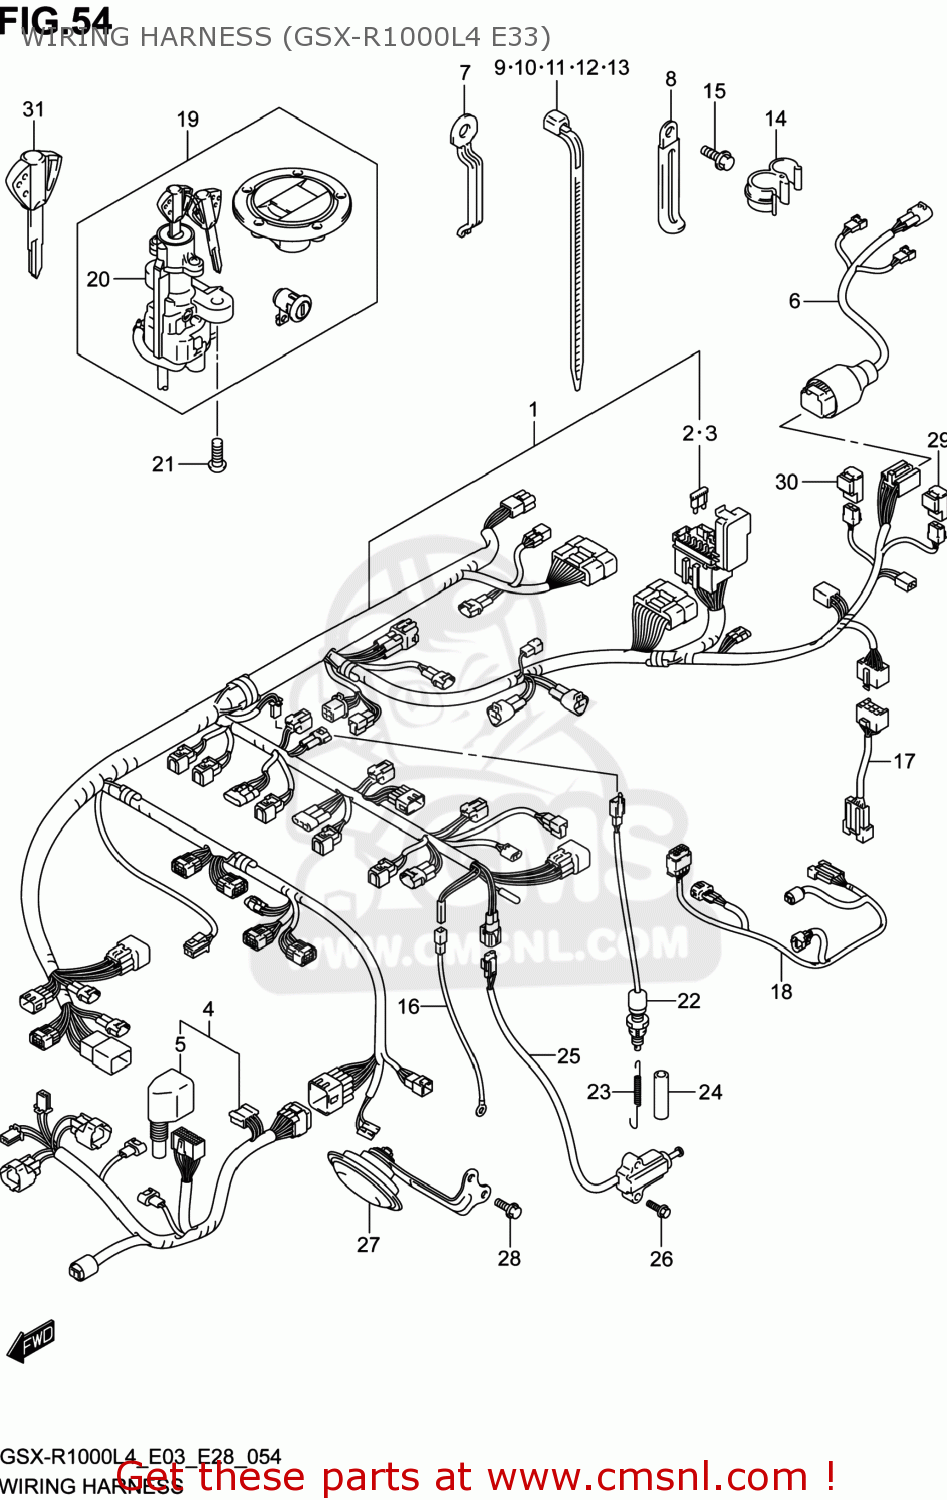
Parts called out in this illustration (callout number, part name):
1	HARNESS,WIRING
2	FUSE(10A)
3	FUSE(15A)
4	HARNESS,WIRING NO.2
5	COVER,CONNECTOR
6	WIRE,RR COMB
7	CLAMP
8	CLAMP(L:45)
9	CLAMP(L:125)
10	CLAMP(L:95)
11	CLAMP(L:165)
12	CLAMP(L:190)
13	CLAMP(L:190)
14	CLAMP
15	BOLT
16	WIRE,OIL PRESSURE SWITCH LEAD
17	WIRE,RELAY LEAD
18	WIRE,ISC LEAD
19	LOCK SET
20	LOCK ASSY,STEERING
21	BOLT(8X20)
22	SWITCH ASSY,STOP LAMP
23	SPRING
24	HOSE(5X8.2X600)
25	SWITCH ASSY,SIDE STAND
26	BOLT(6X20)
27	HORN ASSY
28	BOLT
29	RELAY ASSY
30	RELAY ASSY
31	KEY,BLANK(IMMOBII)
